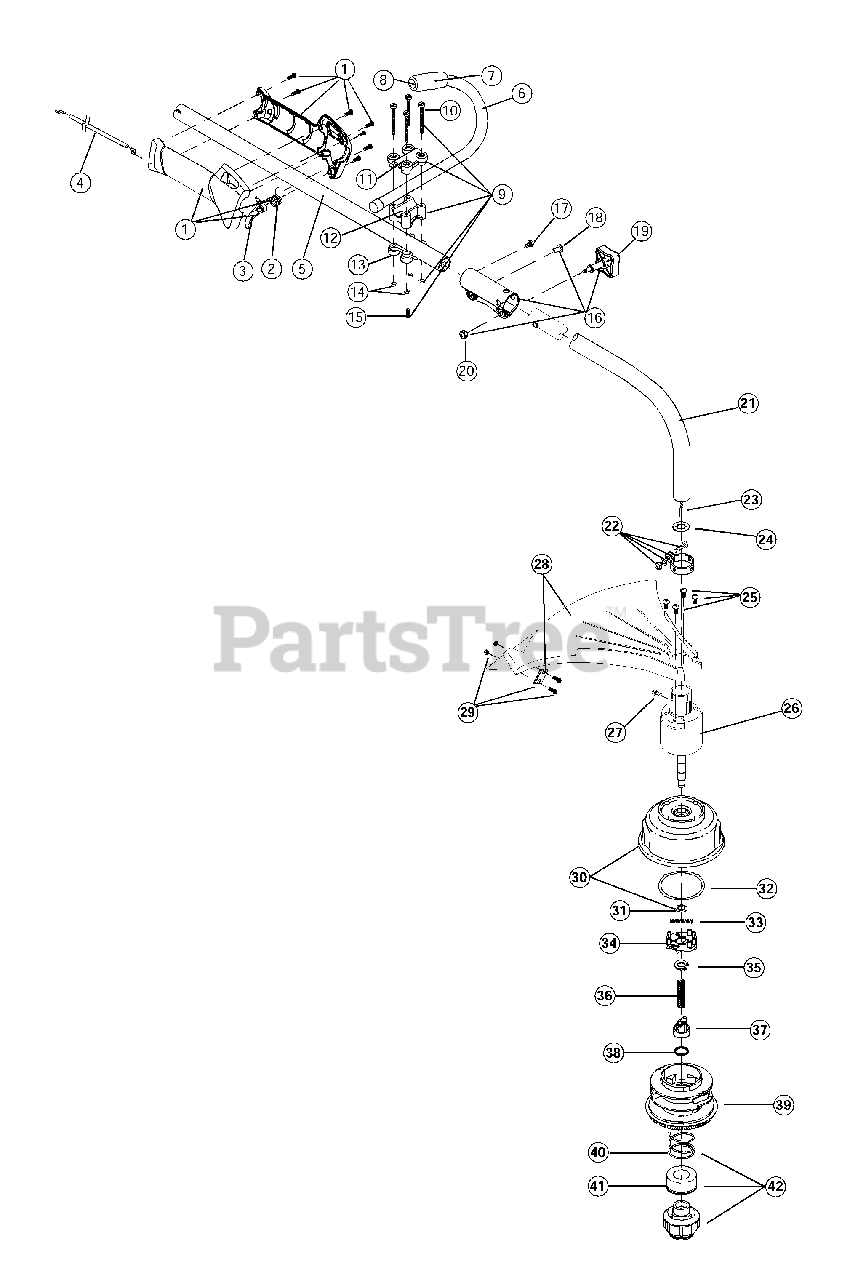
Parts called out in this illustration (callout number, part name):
1	Throttle Housing and Trigger Assembly
2	Throttle Trigger Spring
3	Throttle Trigger
4	Throttle Cable Assembly
5	Upper Drive Shaft Housing Assembly
6	J-Handle Assembly
8	Tube Closure
9	Handle Bracket Assembly
11	Upper Handle Clamp
12	Middle Handle Clamp
13	Lower Handle Clamp
15	Anti-Rotation Screw
16	Slit Boom Coupler
19	Adjustment Knob
20	Knob Retaining Nut
21	Lower Drive Shaft Housing Assembly
22	Lower Clamp Assembly
23	Lower Flexible Drive Shaft
24	Palnut
25	Shield Mounting Screw
26	Bushing Housing Assembly
27	Anti-Rotation Screw
28	Shield and Blade Assembly
29	Blade Assembly
30	Outer Spool Assembly
31	Retainer
32	Thrust Washer
33	Small Spring
34	Slider
37	Plunger
39	Inner Reel
40	Large Spring
41	Foam Seal
42	Bump Head Knob Assembly w/Spring & Foam Seal
